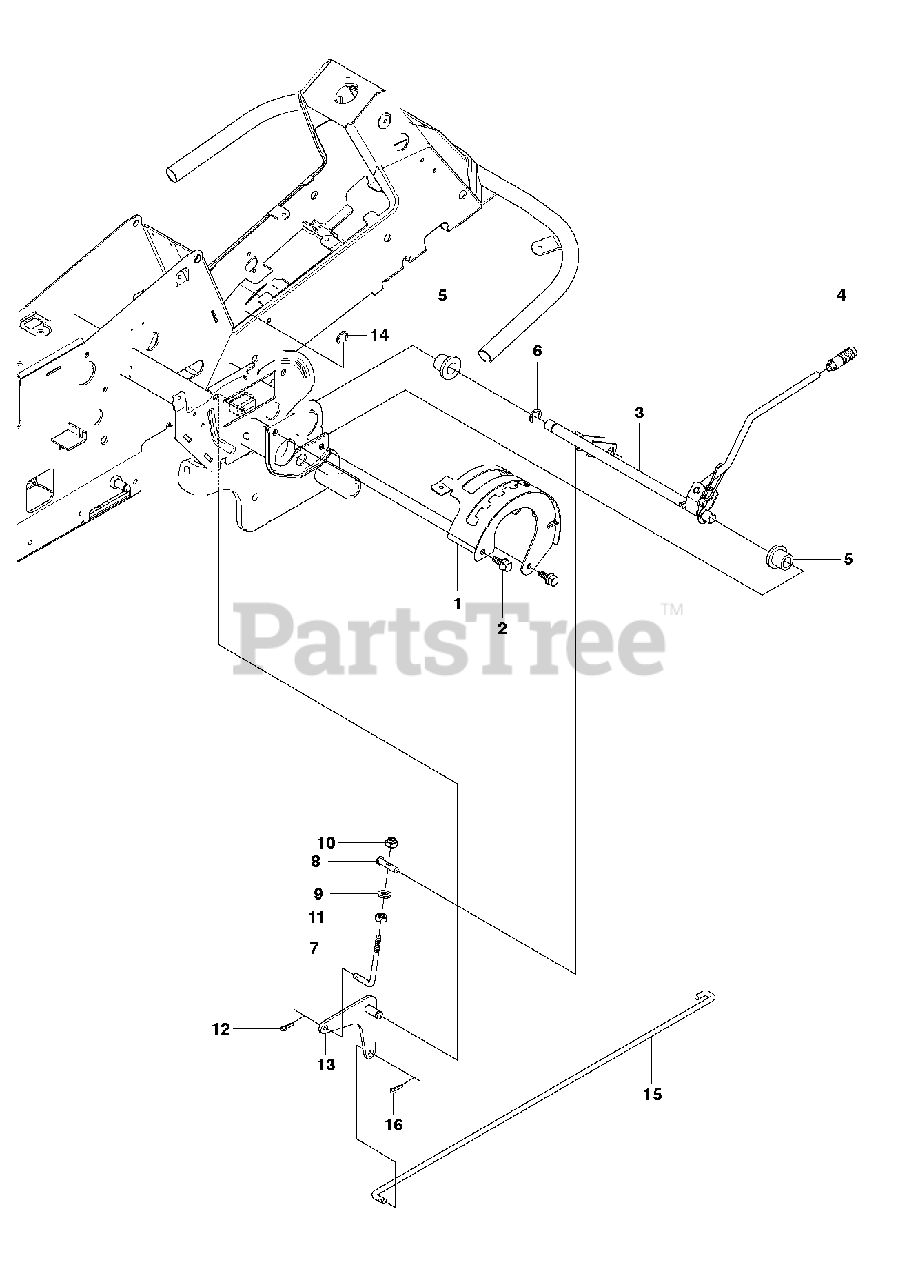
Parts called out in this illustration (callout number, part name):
4	GEAR STICK KNOB
5	BUSHING
9	WASHER
10	LOCKNUT M8
11	NUT
12	SPLIT PIN
14	RETAINING RING
16	SPLIT PIN
